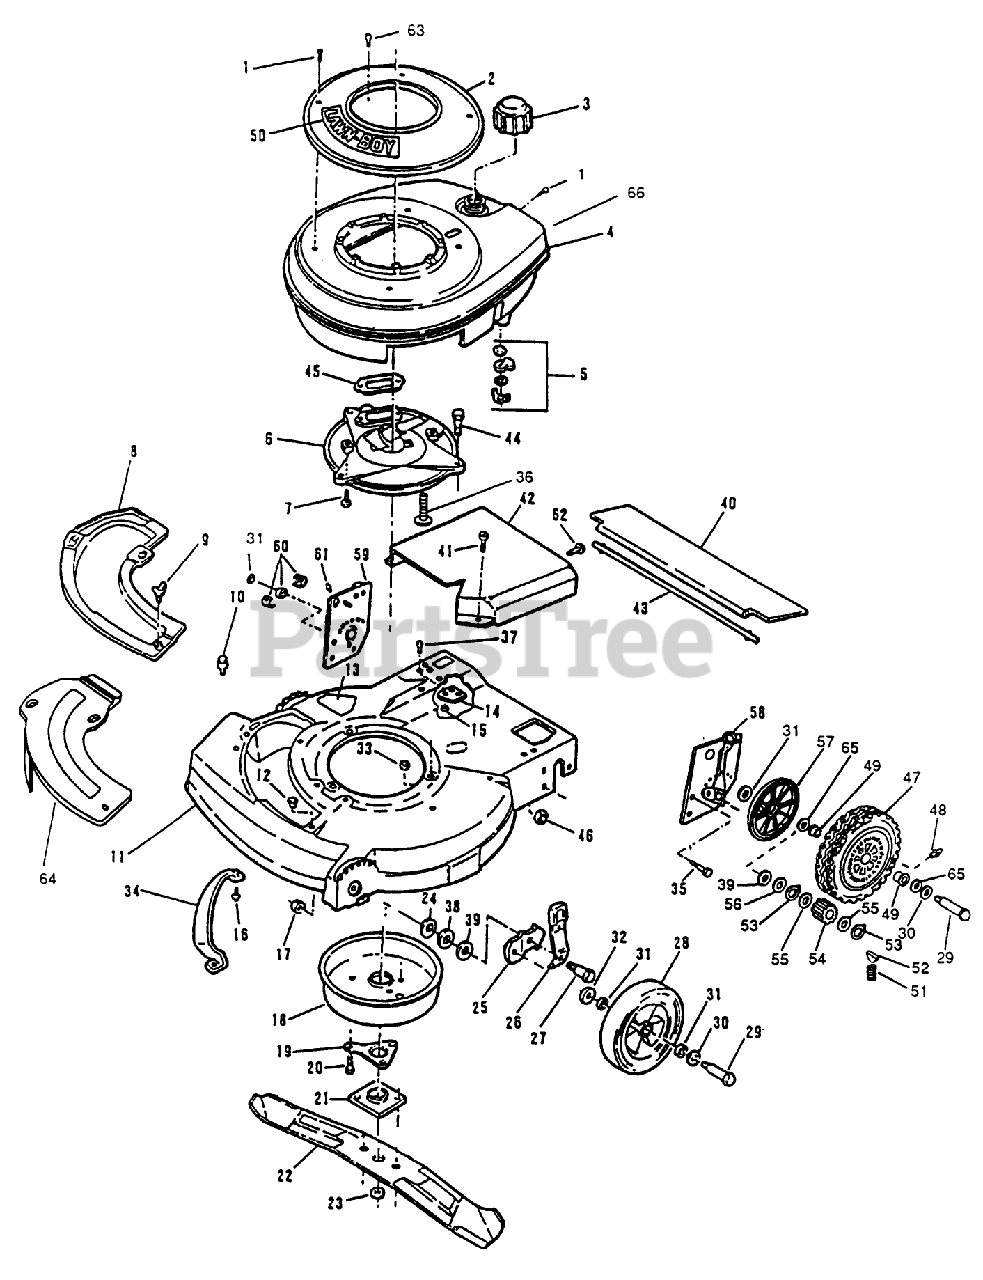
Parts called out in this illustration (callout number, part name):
1	SCREW - SELF TAPPING
2	STARTER BASE&NUT*B
3	FUEL CAP & INSERT
4	SHROUD,TANK&VAL
5	SHUT OFF VALVE KIT
6	PLATE F
7	SCREW V
9	WING SCREW LAWRE
11	HOUSING ASM
14	BOLSTER
15	LOCKNUT E
18	MUFFLER COVER F
19	SUPPORT F
20	SCREW
21	PLATE AND COLLAR ASM
23	NUT-BLADE
24	WASHER
26	SPRING ARM ASM
27	BOLT
29	BOLT WHEEL
30	SPACER
31	WASHER
32	WASHER WROUGHT
33	NUT-LOCK F
34	BAR-TOE
36	SCREW-SEMS F
38	WASHER
39	WASHER
40	SHIELD-TRAILING
41	SCREW SEMS TRM HEX HD
44	SCREW-HH
46	NUT-LOCK F
48	FITTING LINCOLN
51	SPRING
52	KEY
53	RET RING
54	PINION BROCKWAY
55	SPACER/GR ALGHNY
56	THRUST WASHER
59	HEIGHT ADJ AY-RH
60	REAR AXLE BEARING
61	**FITTING LINCOLN
63	SCREW SEMS SM
65	WASHER-FELT
